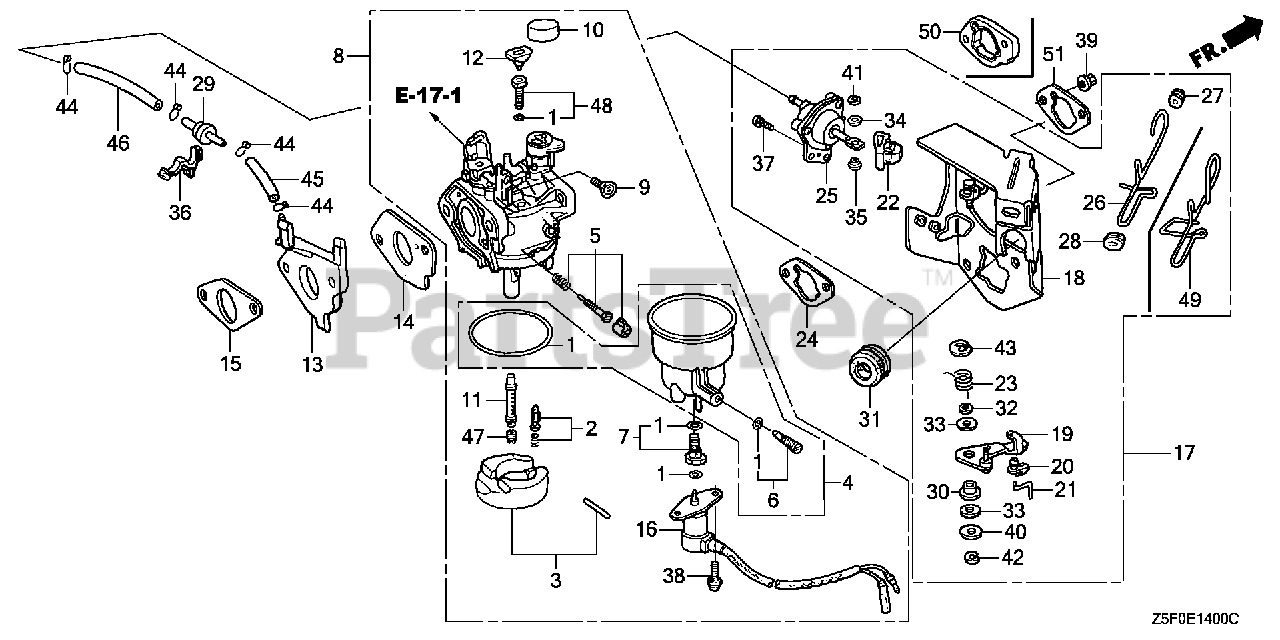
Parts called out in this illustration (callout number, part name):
1	GASKET SET
2	VALVE SET, FLOAT
3	FLOAT SET
4	CHAMBER SET, FLOAT
5	SCREW SET (Honda Code 4219879). (CARBURETOR NO.)
6	SCREW SET, DRAIN (ADVENTURE GREEN) (CARBURETOR NO.)
7	SCREW SET B
8	CARBURETOR ASSY. (BE72L A)
9	SCREW, THROTTLE STOP
10	CAP, CHOKE LEVER DUST
11	NOZZLE, MAIN
12	COLLAR, SET
13	INSULATOR, CARBURETOR
14	GASKET, CARBURETOR
15	GASKET, INSULATOR
16	VALVE ASSY., SOLENOID
17	STAY ASSY., MANUAL CHOKE
18	STAY, SOLENOID
19	LEVER, CHOKE
20	JOINT, ROD
21	ROD, CHOKE
22	STOPPER, CHOKE ROD
23	SPRING, MANUAL CHOKE
24	GASKET, AIR CLEANER
25	DIAPHRAGM ASSY.
27	GROMMET, CHOKE ROD
28	GUIDE, CHOKE ROD
29	VALVE, DASHPOT CHECK
30	BUSH, ARM PIVOT
31	GROMMET, FENDER
32	WASHER, CHOKE LEVER
33	SEAL, CHOKE LEVER
34	WASHER, THRUST (2.7X8)
35	COLLAR, LEVER
36	CLIP, WIRE HARNESS
37	SCREW, PAN (5X12)
38	SCREW-WASHER (5X12)
39	NUT, FLANGE (6MM)
40	WASHER, PLAIN (5MM)
41	E-RING (2MM)
42	E-RING (4MM)
43	E-RING (7MM)
44	CLIP, TUBE (B7)
45	BULK HOSE, VACUUM (3.5X8000) (3.5X130)
46	BULK HOSE, VACUUM (3.5X8000) (3.5X130)
47	JET, MAIN (#75) (CARBURETOR NO.)
47	JET, MAIN (#78) (CARBURETOR NO.)
47	JET, MAIN (#80)
48	JET SET, PILOT (#45)
49	ROD, CHOKE CONTROL
51	GASKET, AIR CLEANER
